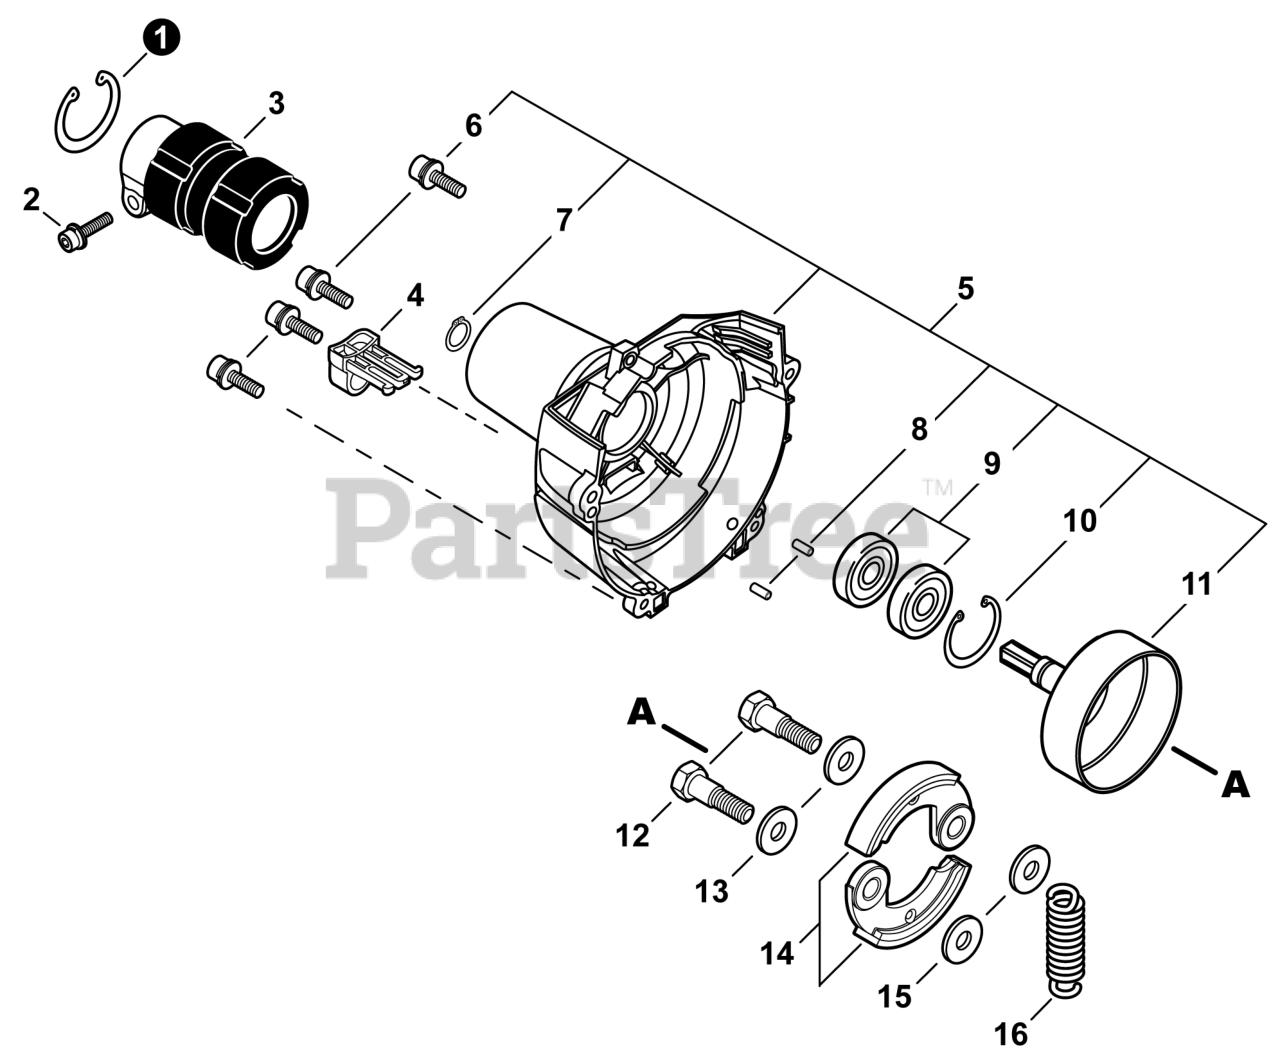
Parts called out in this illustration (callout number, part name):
1	RING, SNAP 42
2	BOLT 5x28
3	HOLDER, MAIN PIPE
5	COVER ASSY, FAN
6	BOLT 4x16
7	RING, SNAP 12
8	PIN, LOCATING 4
9	BEARING, BALL 6001
10	RING, SNAP 28
11	DRUM, CLUTCH
12	BOLT, CLUTCH 8x7.9xM6
13	WASHER, SPRING 8.5x16x0.5
14	SHOE, CLUTCH
15	WASHER 6.2x19x1.0
16	SPRING, CLUTCH
